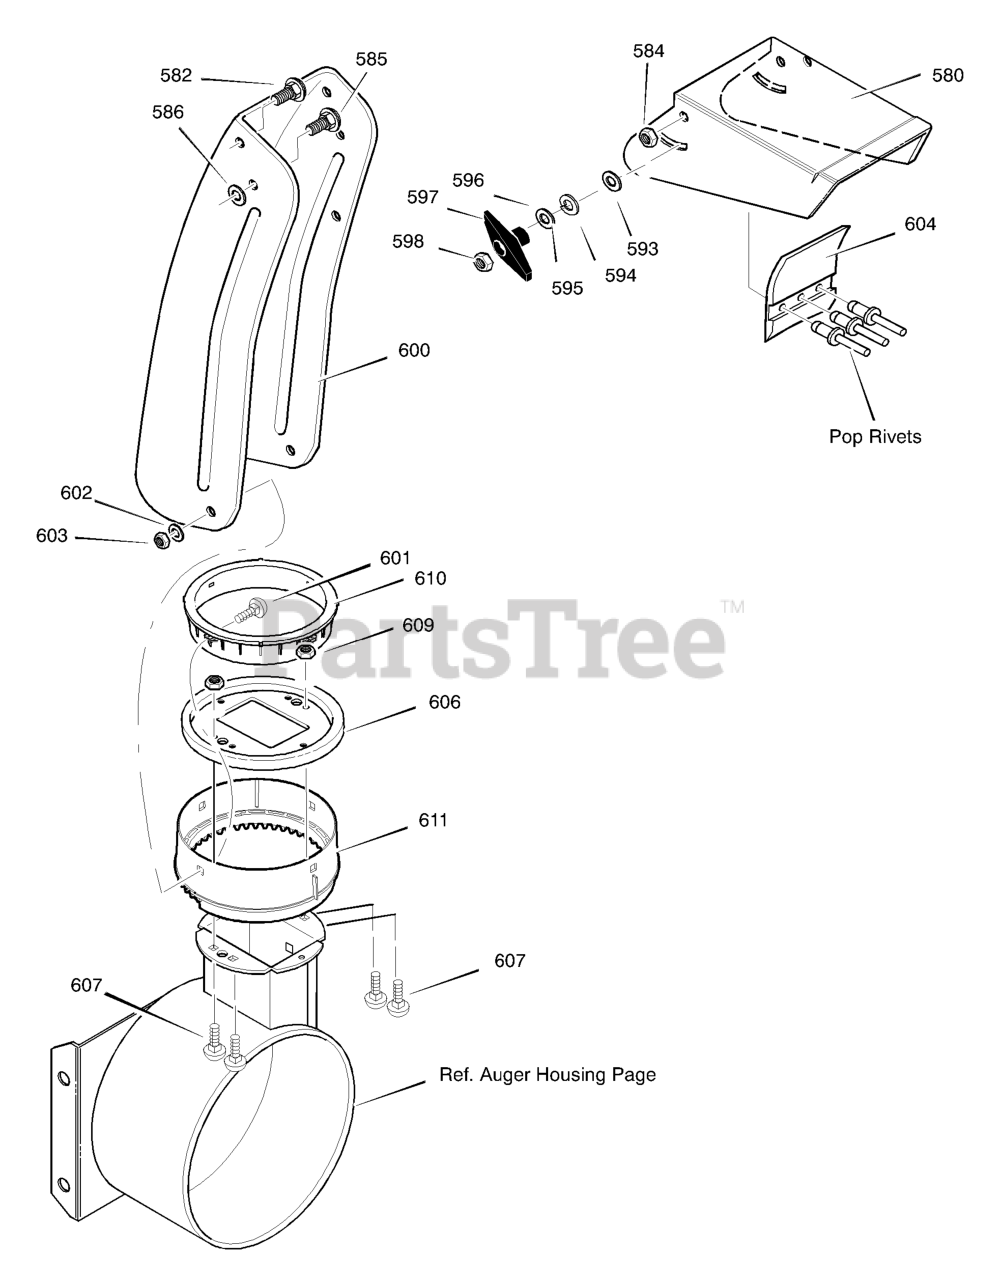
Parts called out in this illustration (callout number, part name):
580	CHUTE, UPPER W/REMOTE
582	SCREW, 5/16-18 x 0.75
584	NUT
585	SCREW, 5/16-18 x 0.75
593	WASHER, PLASTIC
594	WASHER, FLAT
595	WASHER, SPLIT
596	WASHER, FLAT
597	KNOB, T 3.00
598	NUT
600	CHUTE, LOWER / GUARD
602	WASHER, FLAT
603	NUT
606	CHUTE COLLAR
607	BOLT
609	NUT
610	RETAINER, RING INNER
611	RETAINER, RING OUTER
